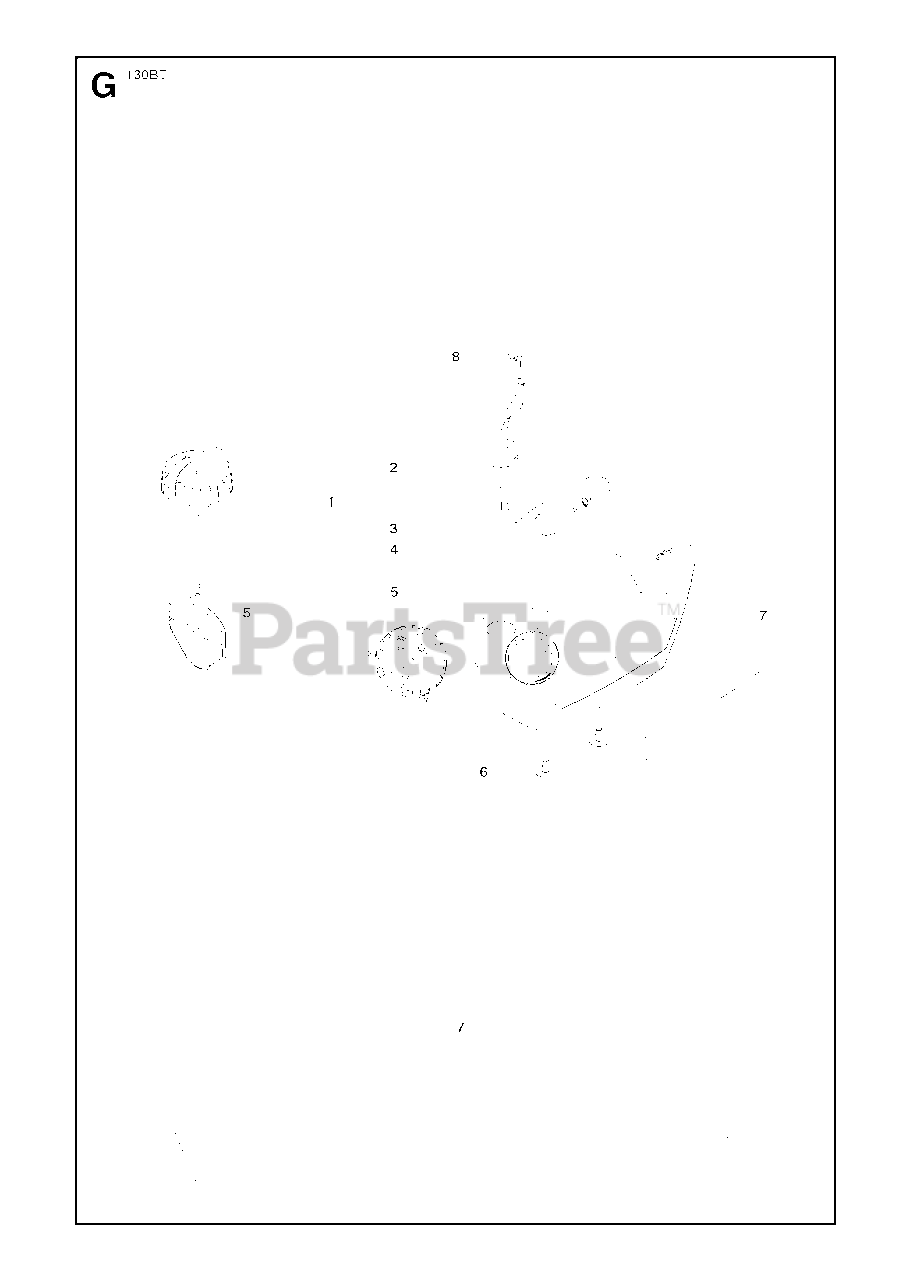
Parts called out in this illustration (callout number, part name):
1	FUEL TANK ASSY EVAP
2	PIPE C
3	FUEL FILTER
4	CLIP
5	FUEL CAP ASSY
8	CLIP
